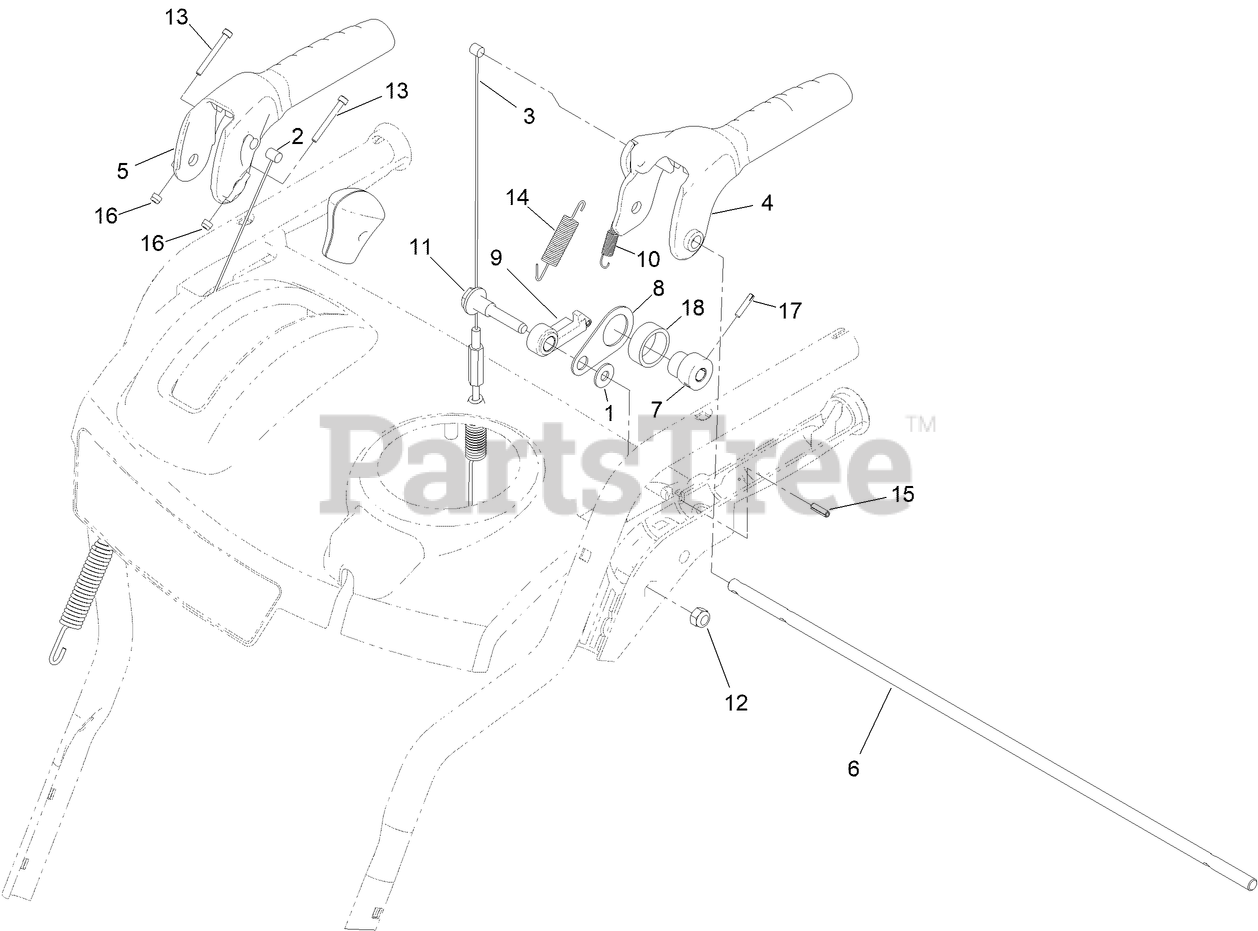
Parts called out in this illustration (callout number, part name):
1	WASHER-FLAT
2	CABLE-AUGER
3	CABLE-TRACTION
4	HANDLE-CONTROL, TRACTION
5	HANDLE-CONTROL, AUGER
6	ROD-LOCKOUT
7	CAM-LOCKOUT
8	LINK-LOCKOUT
9	LATCH-LOCKOUT
10	SPRING-LOCKOUT, HANDLE
11	SCREW-SHOULDER
12	NUT-HEX
13	SCREW-HSH,SPL
14	SPRING-RETURN, LEVER
15	PIN-ROLL, SLOTTED
16	NUT-LOCK ROHS
17	PIN-QUARTER GROOVE
18	SPACER-PLASTIC
